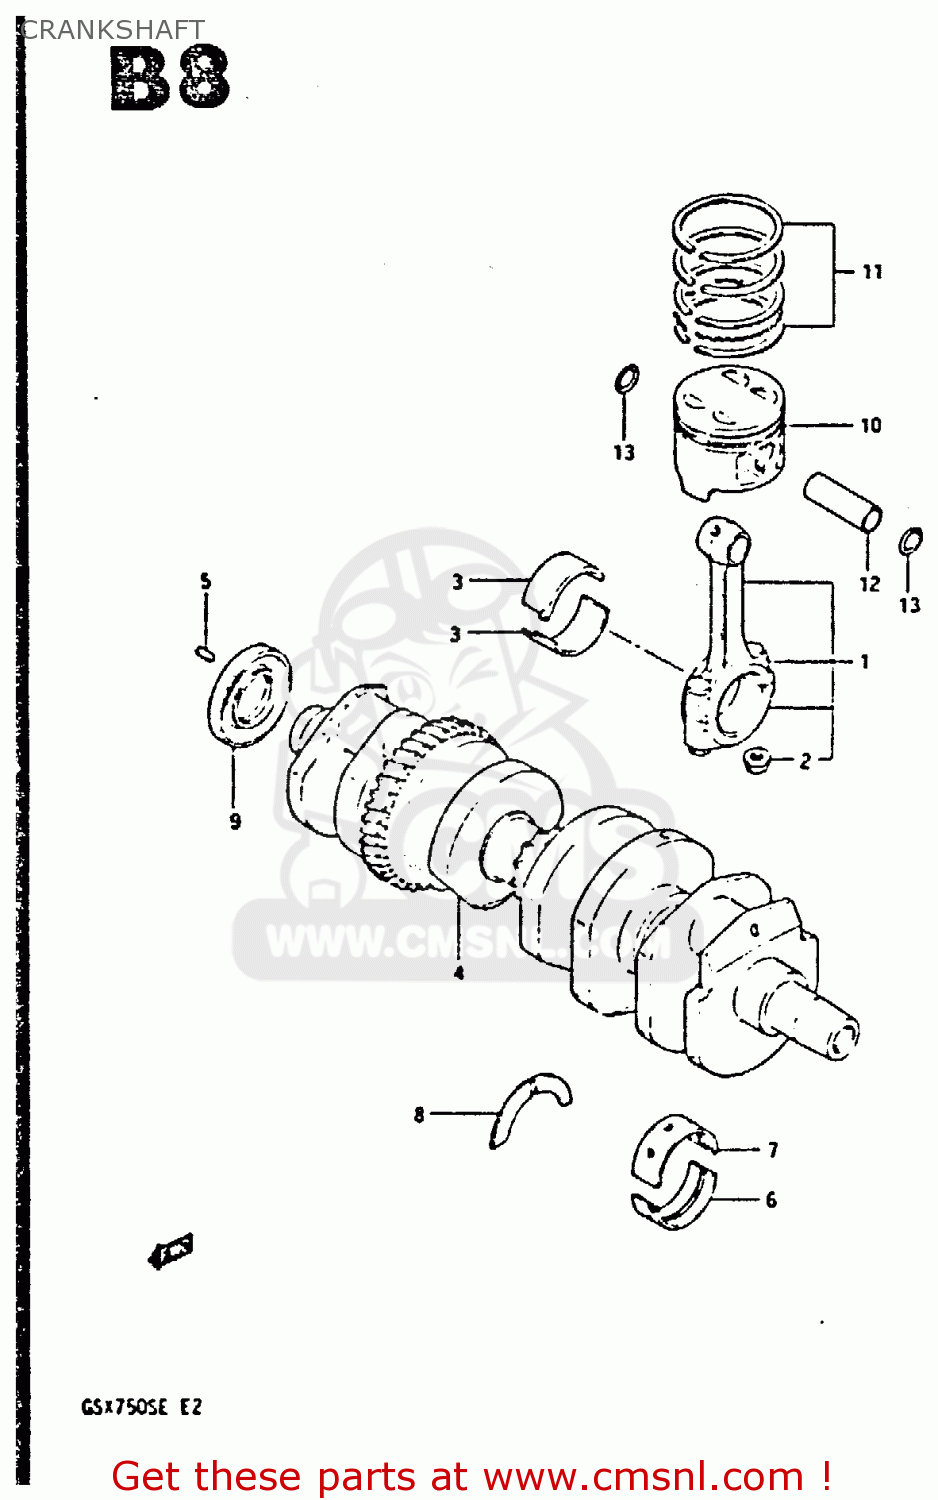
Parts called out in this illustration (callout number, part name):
1	ROD ASSEMBLY,CONNECTING
2	NUT
3	METAL,CRANK PIN
4	CRANKSHAFT ASSEMBLY
5	PIN
6	METAL,CRANKSHAFT (GREEN)
7	METAL CRANKSHAFT (GREEN)
8	PLATE,CRANK THRUST
9	SEAL,OIL(30X60X8)
10	PISTON
11	RING SET,PISTON
12	PIN,PISTON
13	CIRCLIP,PISTON PIN
